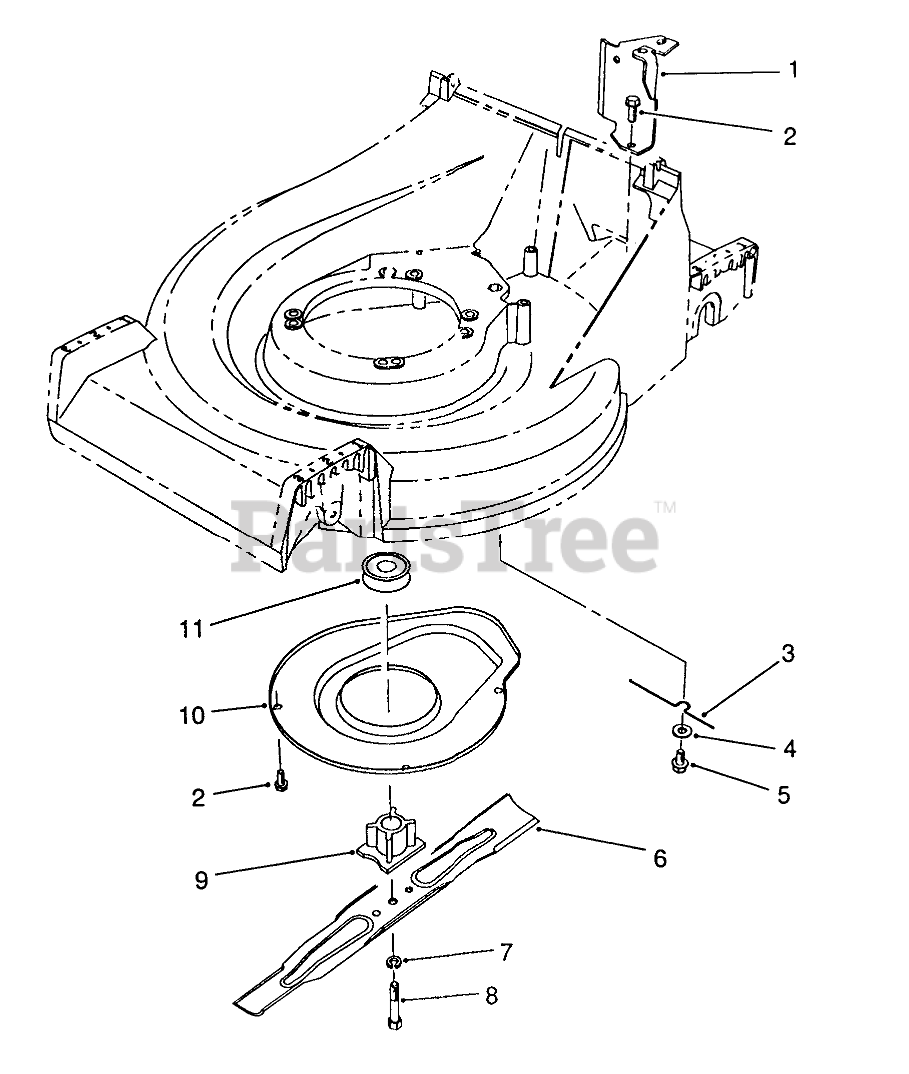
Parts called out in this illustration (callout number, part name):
1	Bracket-Cable Support
2	SCREW-HWHTF
3	RETAINER-BELT
4	WASHER-FLAT
5	SCREW-HHFTF
6	Key
7	WASHER-LOCK
8	SCREW-BLADE
9	BLADE RETAINER
10	Cover
11	PULLEY-DRIVE, ZONE START
